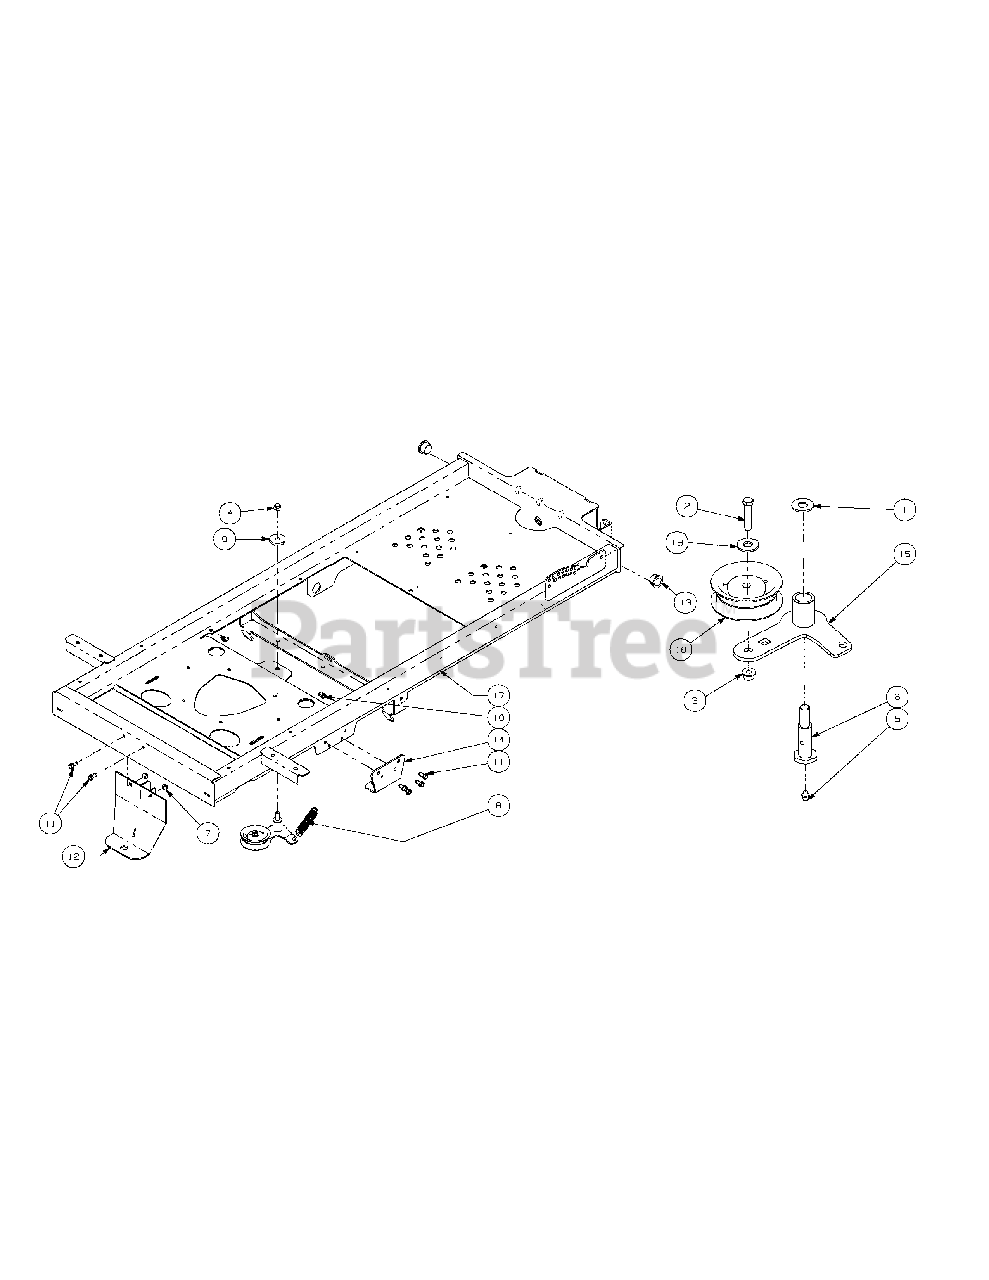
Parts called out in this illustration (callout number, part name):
1	Flat Washer, 3/8 zinc
2	Hex Cap Screw, 3/8-16 x 1-3/4
3	Hex Nut, 3/8-16 Flange Lock
4	Nylock Nut, 7/16-14
5	Grease Fitting, 1/4-28 x 3/16
6	Shoulder Bolt
7	Nut, 5/16-18, Hexflange Lock
8	Extension Spring, 1.00 OD x 5.00 lg
9	Flat Washer, 7/16 ID x 1.75 OD
10	U-Nut, 1/4-20
11	Self Tapping Screw 5/16-18 x .750
13	Bronze Bushing, 1.00 ID x 1.50 OD
14	Transmission Mounting Bracket
15	Idler Arm Assembly includes:
16	Flat Idler Pully w/ adaptor
17	Frame Assembly Weldment
18	Washer, 3/8, SS
